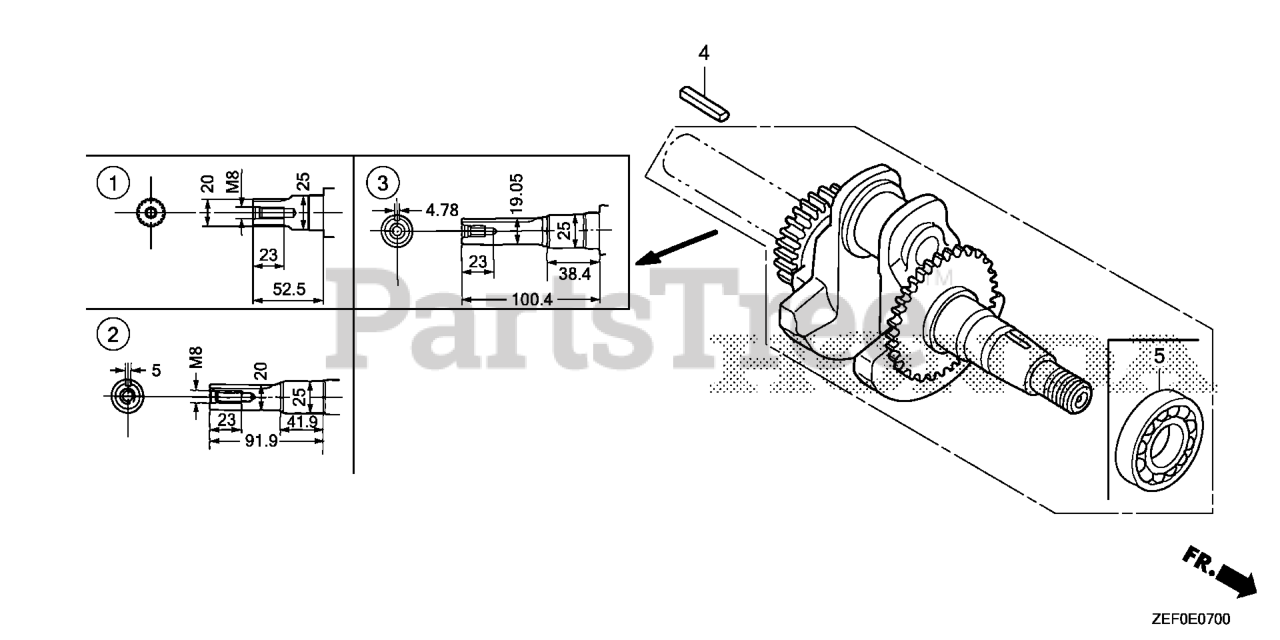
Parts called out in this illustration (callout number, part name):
3	CRANKSHAFT
5	BEARING, RADIAL BALL (6205)
5	BEARING, RADIAL BALL (6205) (NSK)
